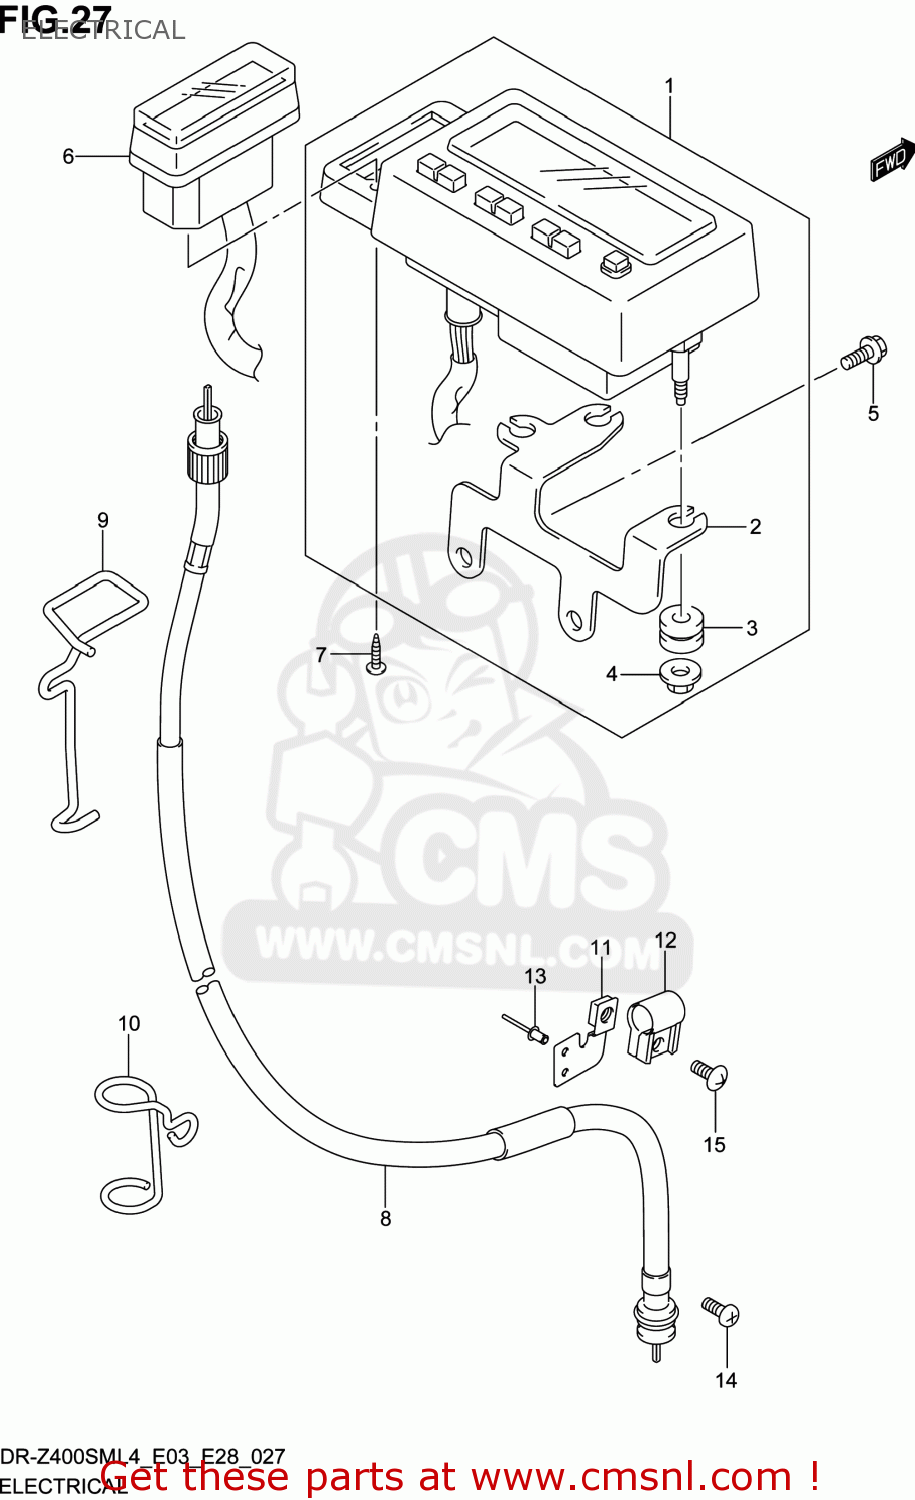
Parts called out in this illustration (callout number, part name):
1	RELAY ASSY,STARTING MOTOR
2	BRACKET,STARTING MOTOR RELAY
3	PROTECTOR,STARTING MOTOR LEAD
4	SCREW(6X8)
5	BOLT
6	RECTIFIER ASSY
7	SCREW
8	CDI UNIT
9	CUSHION(30X50X3)
10	COIL ASSY,IGNITION
11	BOLT
12	CAP,SPARK PLUG
13	SEAL,SPARK PLUG
14	SEAL,HIGH TENSION CORD
15	COVER,SPARK PLUG CAP
